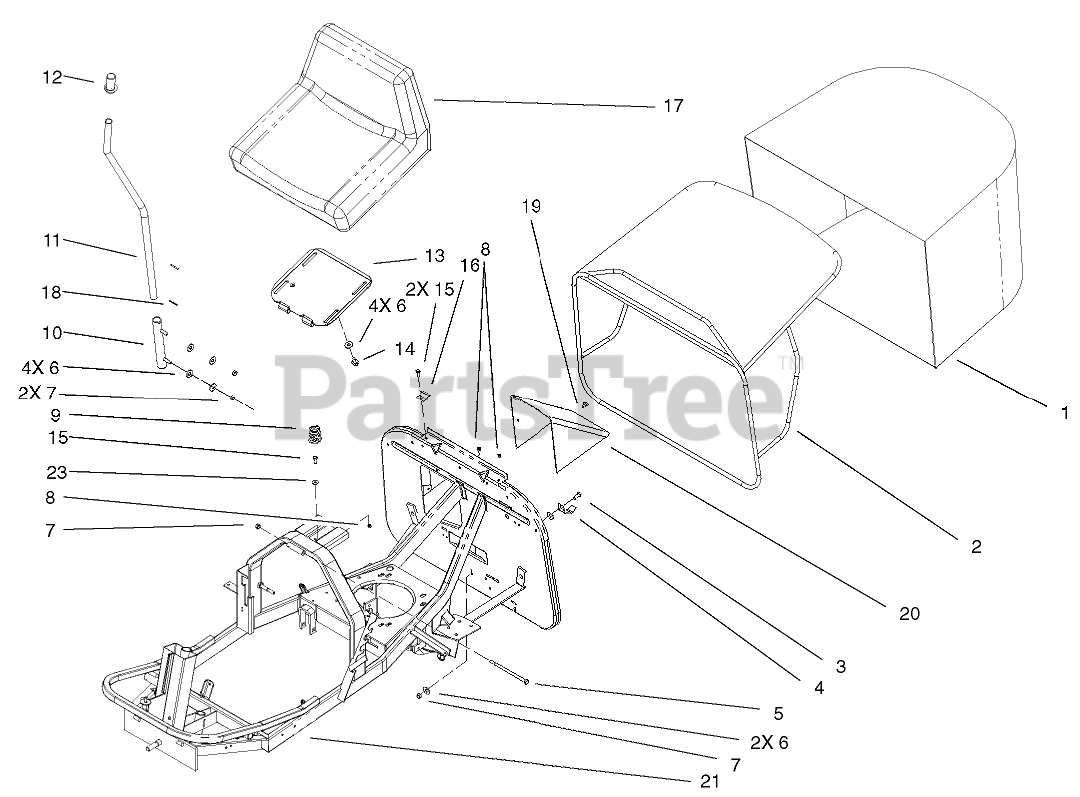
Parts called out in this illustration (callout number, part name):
1	BAG-GRASS
2	Frame-Bag
3	SCREW-HH
4	Hook-Bag
5	Screw-HH
6	Washer-Flat
7	NUT-LOCK
8	NUT-LOCK
9	Spring-Compression
10	Support
11	Lever
13	Plate-Seat
14	SCREW-HHF
15	SCREW-HH
18	Pin-Spring
19	SCREW-HHF
20	Deflector-Rear Discharge
23	Washer-Flat
